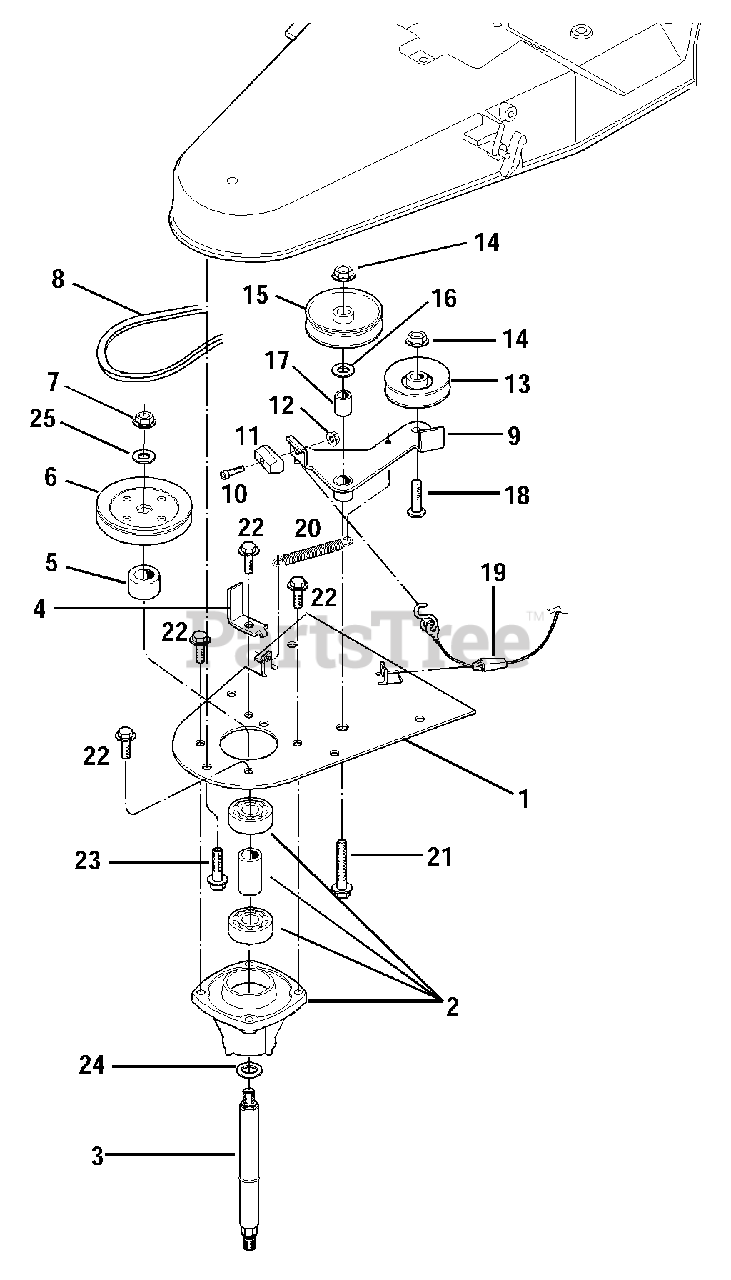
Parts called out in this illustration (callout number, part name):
1	Spindle Mounting Plate
2	Spindle Assembly
3	Spindle Shaft Assembly
5	Spindle Spacer
6	Spindle Pulley
7	Hex Flange Nut, 1/2-13
9	Idler Arm/Brake Shoe Assembly
10	Socket Hd Capscrew, 10-24 x 3/4
11	Brake Shoe
12	Hex Lock Nut, 10-24
13	V-Groove Idler Pulley
14	Hex Flange Nut, 3/8-16
15	Flat Idler Pulley
16	Washer, .88 x .382 x .275
17	Idler Arm Spacer
18	Button Head Screw, 3/8-16 x 1-1/2
19	Control Cable
20	Idler Tension Spring
21	Hex Flange Screw, 3/8 x 16 x 2-1/4
22	Hex Flange Screw, 5/16-18 x 3/4
23	Hex Flange Screw, 5/16-18 x 1
24	Hardened Shim, 3/4 ID x 1.022 OD x .060 thick
25	Belleville Washer, 5/8
